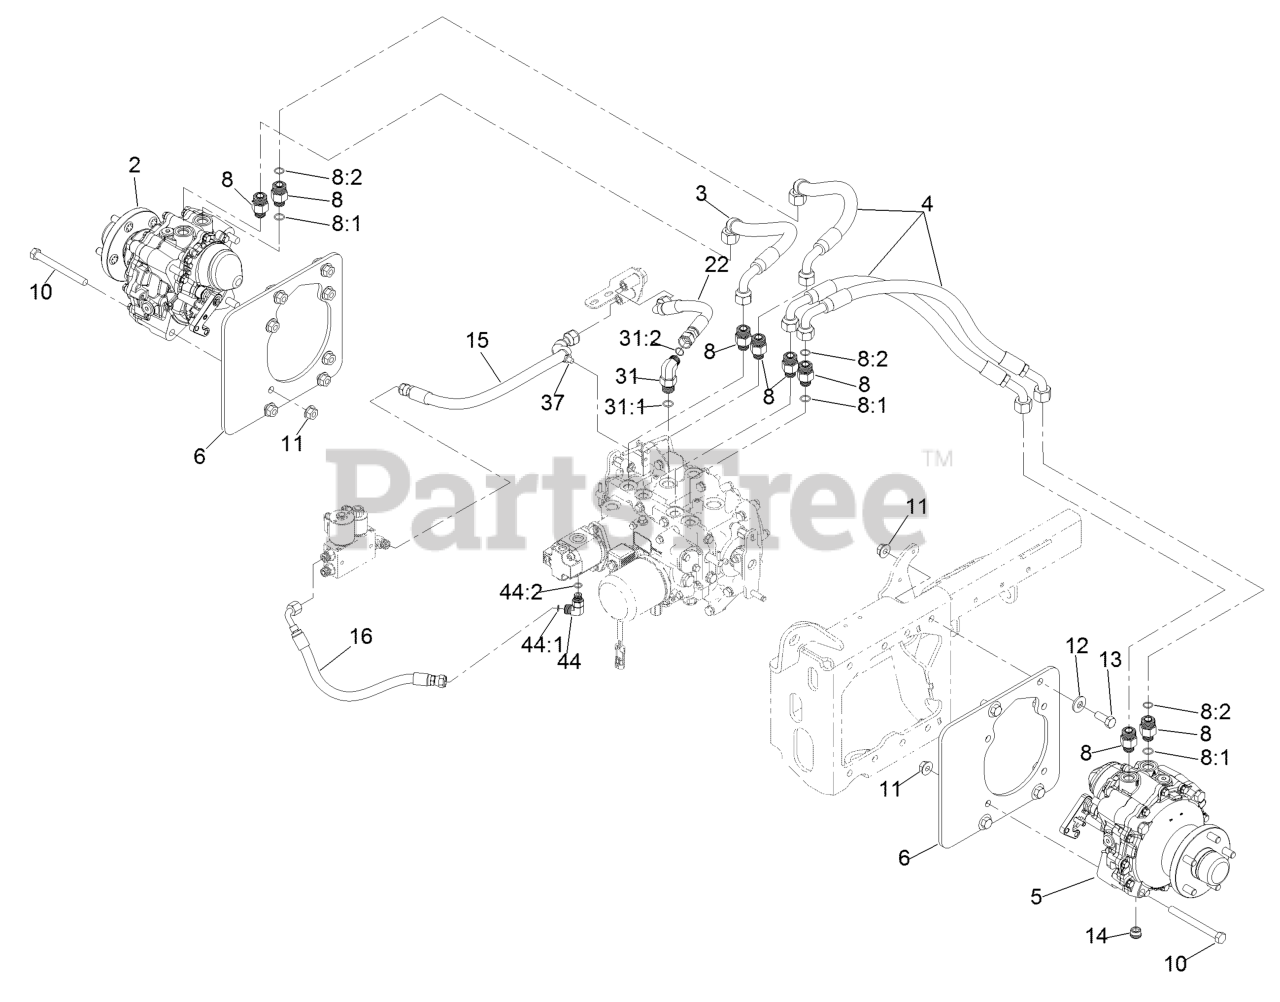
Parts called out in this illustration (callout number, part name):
2	Motor-HYD, RH
3	Hose ASM
4	Hose ASM
5	Motor-HYD, LH
6	Plate-Motor
8	Fitting-Straight
8:1	O-Ring
10	Screw-HH 1/2-13 X 5
11	Nut-Whizlock 1/2-13
12	Washer-Spring Disc 1/2
13	Screw-HH 1/2-13 X 1 1/4
14	Plug-Magnetic
15	Hose ASM
16	Hose ASM
22	Hose ASM
31	Fitting-Elbow, 90 DEG
31:1	O-Ring
31:2	O-Ring
37	Clip-Tie
44	Fitting-Elbow, 90 DEG
44:1	O-Ring
44:2	O-Ring
